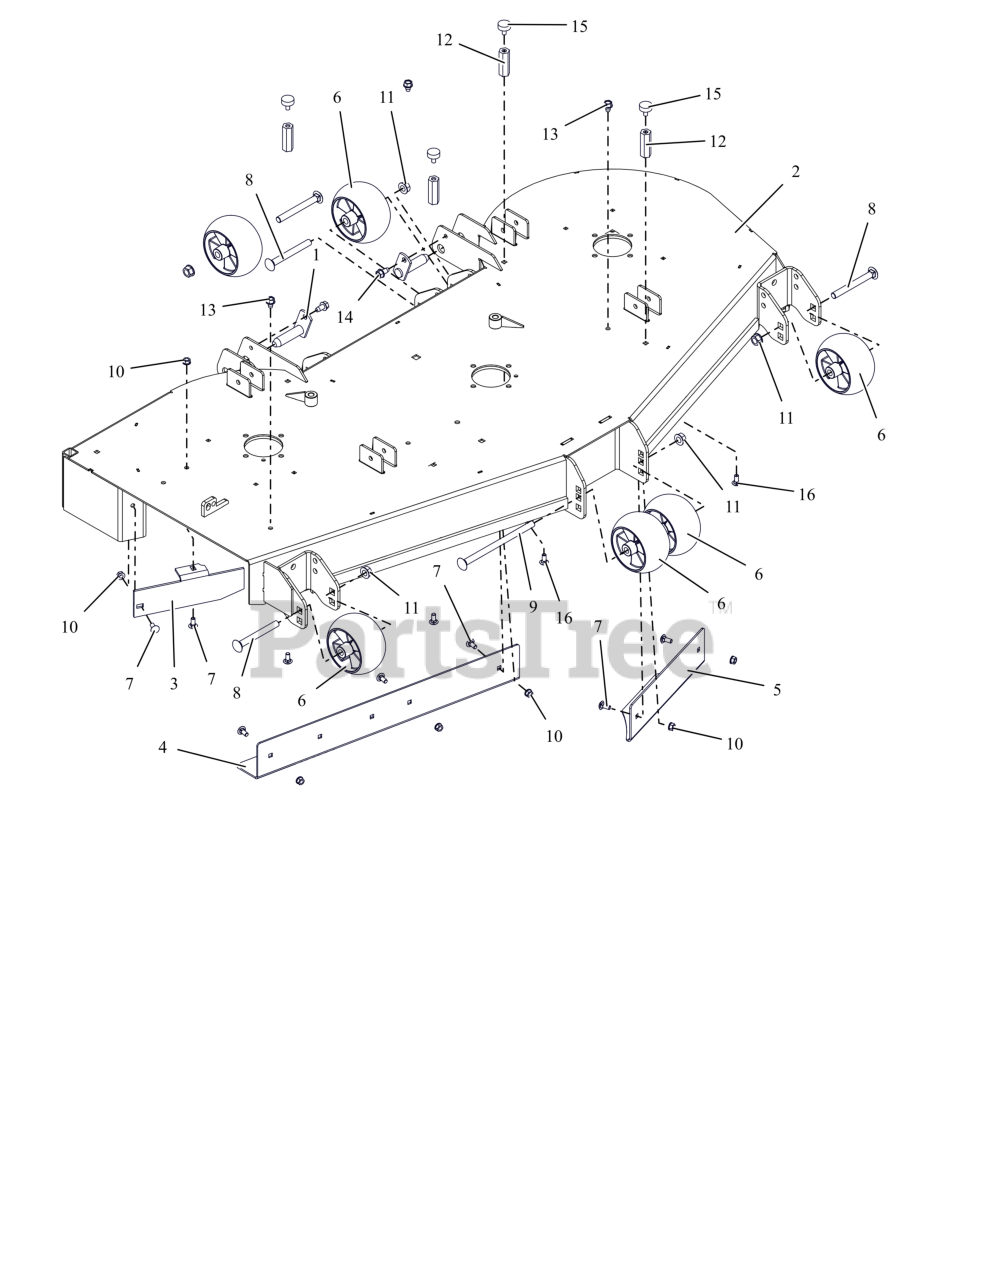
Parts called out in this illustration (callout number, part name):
1	WLDMT, MOWER MTG. PIN (BLACK)
2	KIT, 60" PRO-WALK DECK W/ DECALS (RED)
3	60" DISCHARGE BAFFLE - RED
4	BAFFLE, 60" RH VACUUM (RED)
5	BAFFLE, 60" LH VACUUM (RED)
6	WHEEL, ANTI SCALP - 5X3 CTR W/RIBS
7	BLT,RHSN .31-18X.75 G5 ZCC
8	BLT,RHNS .50-13X4.50 G5 ZCC NS
9	BLT,RHSN .50-13X8.00 G5 ZCC NS
10	NUT,LK-CTR-FLG .31-18 GF ZCC
11	NUT-LK-CTR-FLG .500-13 GG ZCC
12	NUT, .31-18X2.25 LG COUPLING
13	SCR,TAP .375-16X.50 HWH TR ZCC
14	SCR,TAP .375-16X.75 HWH TR ZCC
15	BUMPER, RUBBER
16	BTL,RHSN .313-18 X 0.75 G5 ZCC LT
